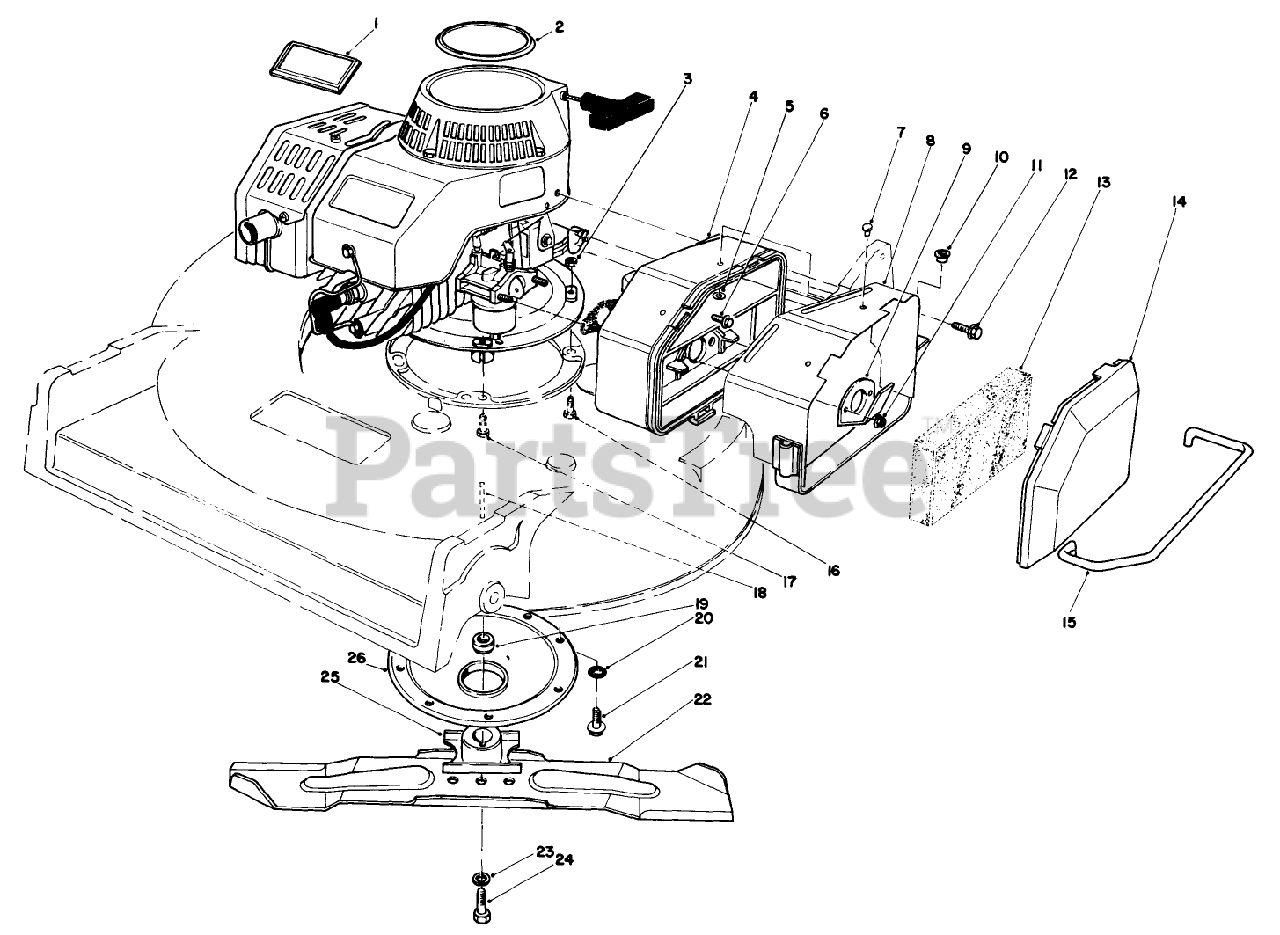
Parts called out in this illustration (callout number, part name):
3	NUT-JAM
4	AIR CLEANER ASM
5	WASHER-FLAT
7	RIVET-POP
9	Dipstick-Oil
12	SCREW-HHF
13	Filter-Foam
15	AIR CLEANER GUARD*
16	SCREW-HH
17	SCREW-HH
18	KEY-SQUARE
19	SPACER-BLADE RETAINER
20	WASHER-LOCK, INTERNAL
21	SCREW-HWHTF
23	WASHER-LOCK
24	SCREW-BLADE
26	PROTECTOR-CRANKSHAFT
